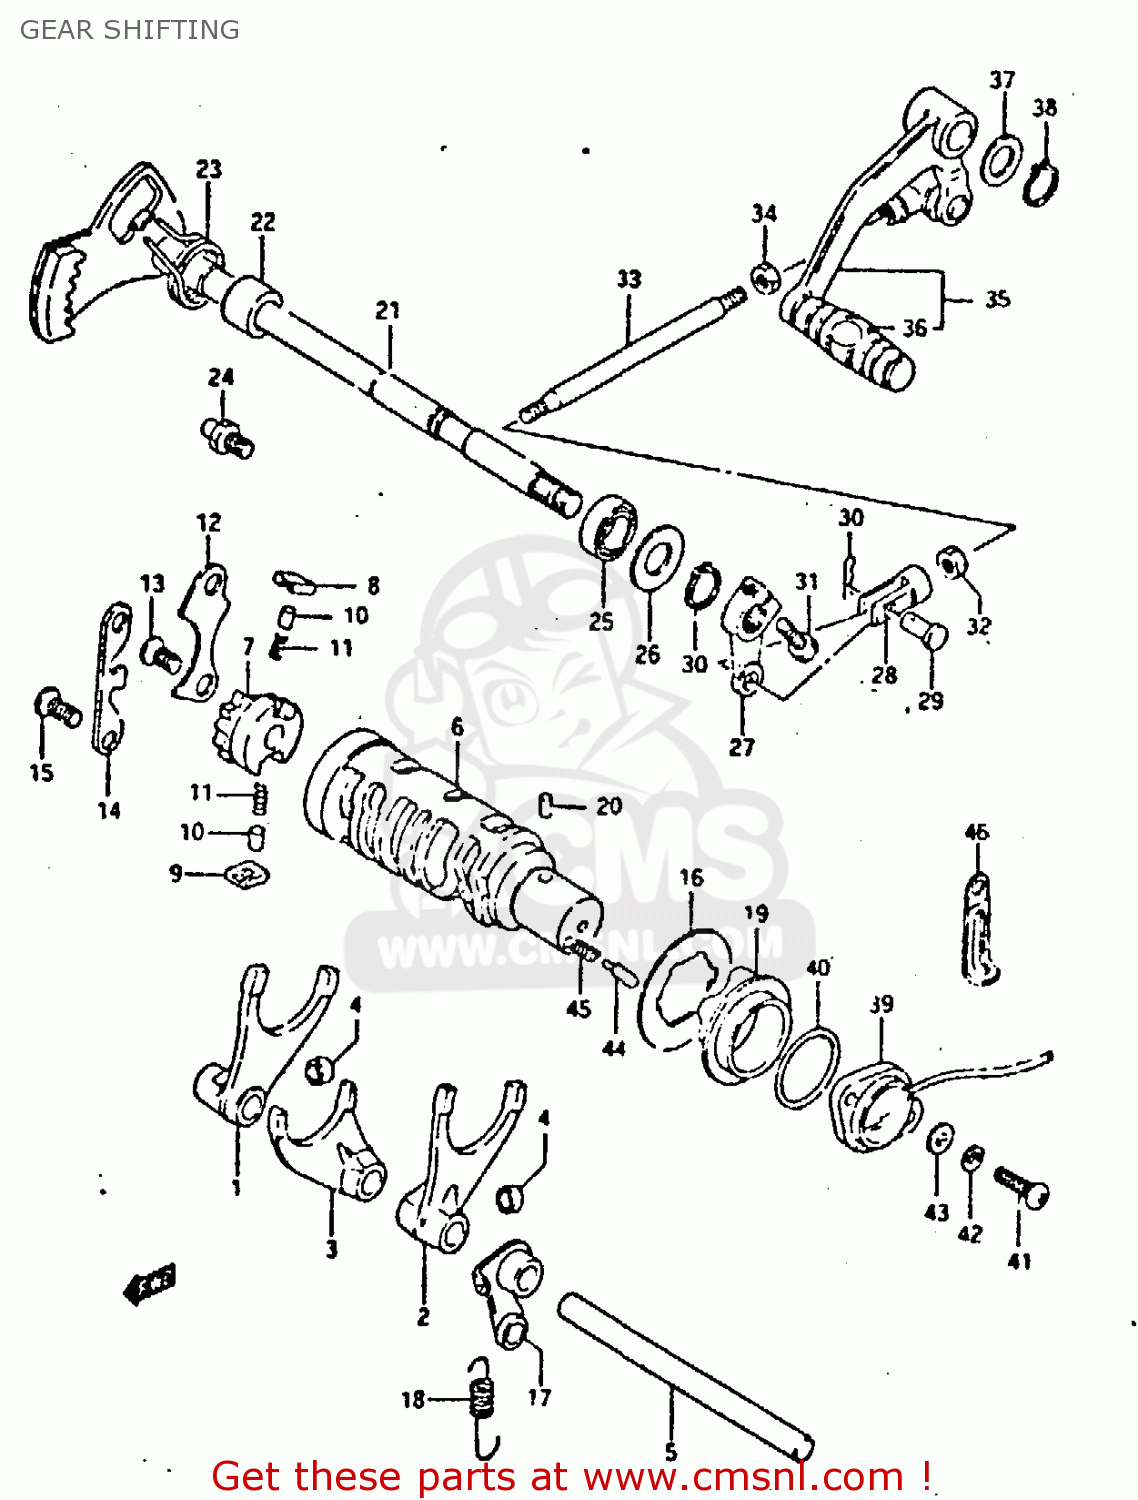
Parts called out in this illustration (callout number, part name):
1	FORK,GEAR SHIFT NO.1
2	FORK,GEAR SHIF
3	FORK,GEAR SHIFT NO.3
4	SPACER(6X9.8X6)
5	SHAFT,GEAR SHIFT FORK
6	SCHAKELWALS
7	GEAR,GEARSHIFT CAM DRIVE
8	PAWL,GEAR SHIFT NO.1
9	PAWL,GEAR SHIFT NO.2
10	PIN(5X8)
11	SPRING
12	LIFTER,GEAR SHIFT PAWL
13	SCREW
14	GUIDE,GEAR SHIFT CAM
15	SCREW
16	WASHER,LOCK
17	STOPPER,GEAR SHIFTING
18	SPRING
19	PLATE,STOPPER
20	PIN 4X6
21	SCHAKELAS
22	SPACER(12X20X15.3)
23	SPRING
24	STOPPER,GEAR SHIFT ARM
25	OIL SEAL
26	WASHER (14.2X22X1)
27	SCHAKELARM
28	JOINT,GEAR SHF
29	PIN,GEAR SHIFT LINK
30	CLIP
31	BOLT
32	NUT 6MM
33	ROD,GEAR SHIFT LINK
34	NUT
35	PEDAALSET.VERSN
36	RUBBER,GEAR SHIFT PEDAL
37	WASHER(12.5X20X1)
38	CIRCLIP
39	TERMINAL BASE,NEUTRAL
40	O-RING (D:2.4 ID:26.2)
41	SCREW
42	WASHER,LOCK
43	WASHER,5MM
44	PIN(5X15.5)
45	SPRING
46	CLAMP
